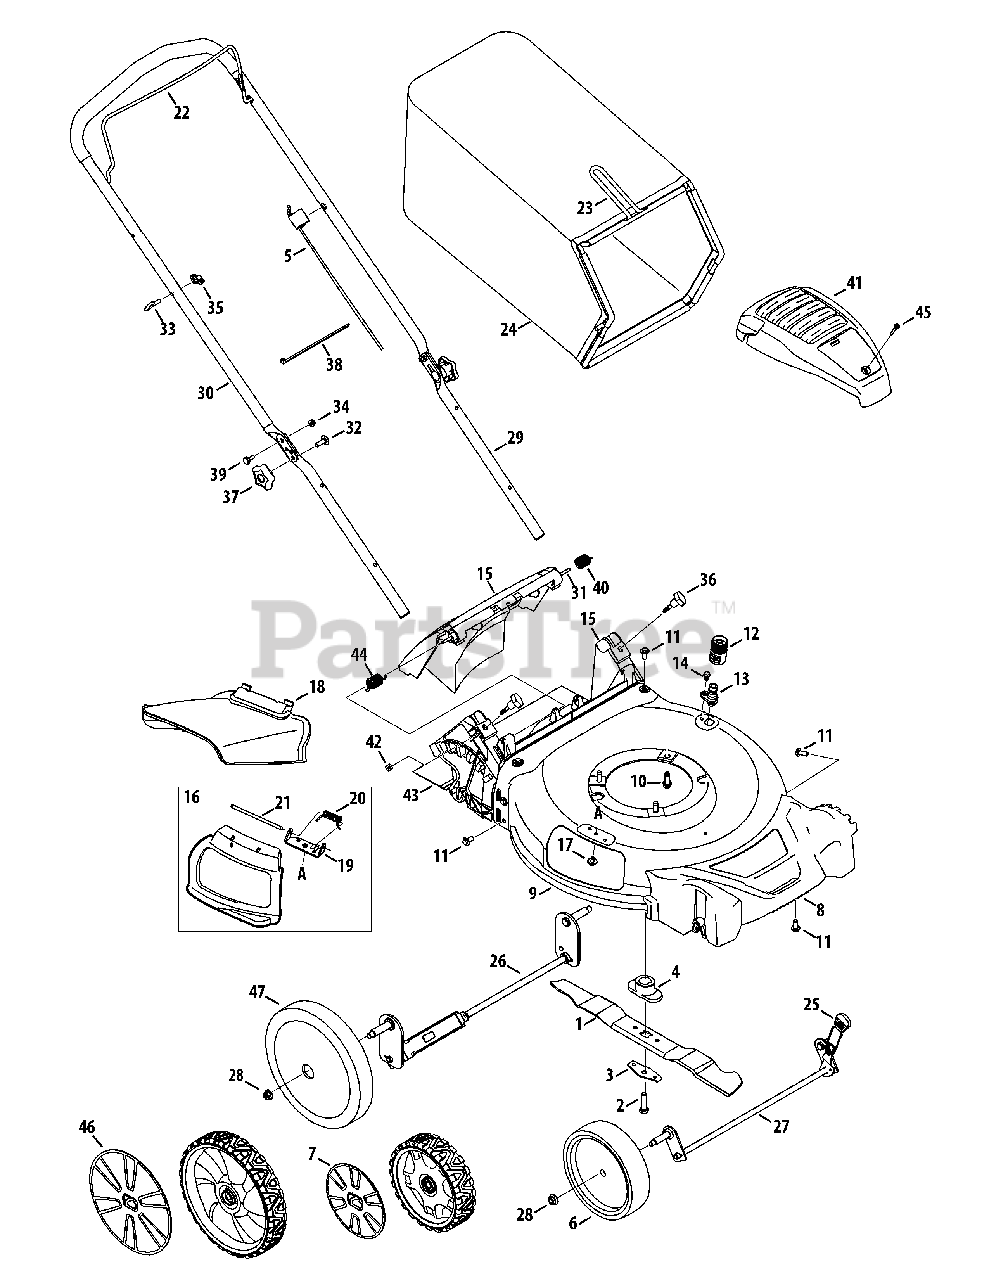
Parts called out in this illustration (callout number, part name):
1	Mulching Blade
2	Screw, 3/8-24 x 1.50
3	Blade Bell Support
4	Blade Adapter
5	Control Cable
6	Wheel, 8 x2
8	Front Cover
10	Screw, tt, 3/8-16 x 1.00
11	Screw, 5/16-14 x .750
12	Water Nozzle Adapter
13	Water Nozzle
14	Shoulder Screw, 1/4-20 x 0.50
15	Rear Discharge Door Assembly
16	Mulch Plug (Incl. 19-21)
18	Side Discharge Chute
19	Chute Deflector Bracket
20	Torsion Spring
22	Blade Control
23	Grass Catcher Frame
24	Grass Bag Only - Black
24	Grass Bag - Signature Cut Series
25	Adjustment Knob
26	Rear Axle Assembly
27	Front Axle Assembly
28	Flange Lock Nut, 3/8-16
29	Lower Handle
32	Carriage Screw ,5/16-18
33	Rope Guide
34	Nut, Flange Lock, 1/4-20
38	Cable Tie
39	Shdr. Screw, .375 x .126 x 1/4-20
40	Torsion Spring - LH
41	Engine Shroud
42	Nut, Sq., 1/4-20
43	Trail Shield
44	Torsion Spring - RH
45	Screw, #10-16 x 1.25
46	Hubcap, 11"
47	Rear Wheel, 11 x 2.0, Zag, Black
